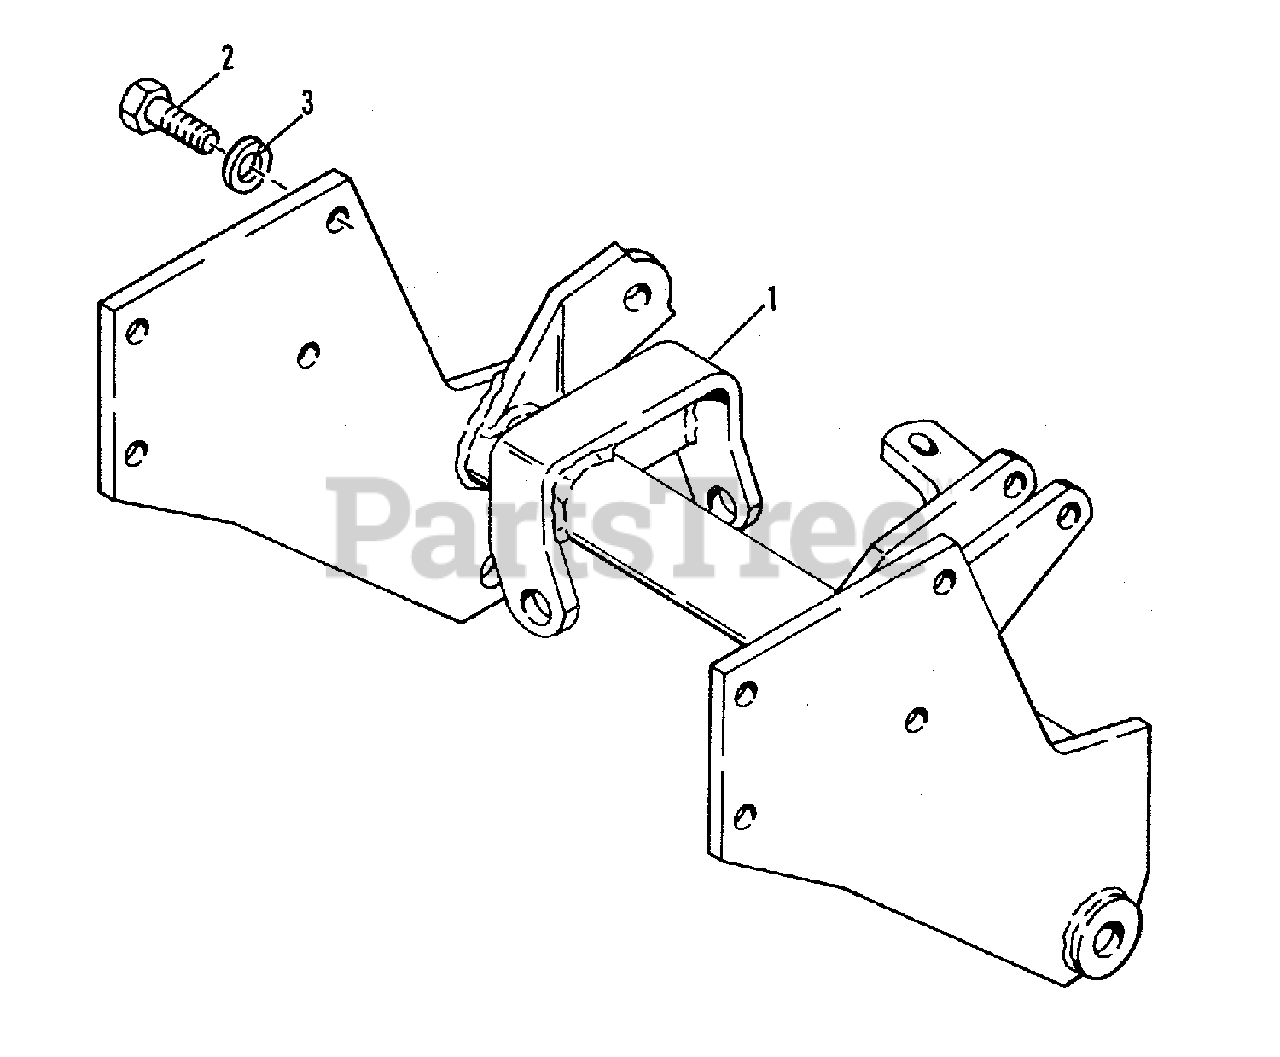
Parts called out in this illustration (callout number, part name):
1	HITCH SUPPORT ASSEMBLY
2	HEX CAPSCREW, 1/2-13 x 1/4" Lg.
3	LOCKWASHER, 1/2"
